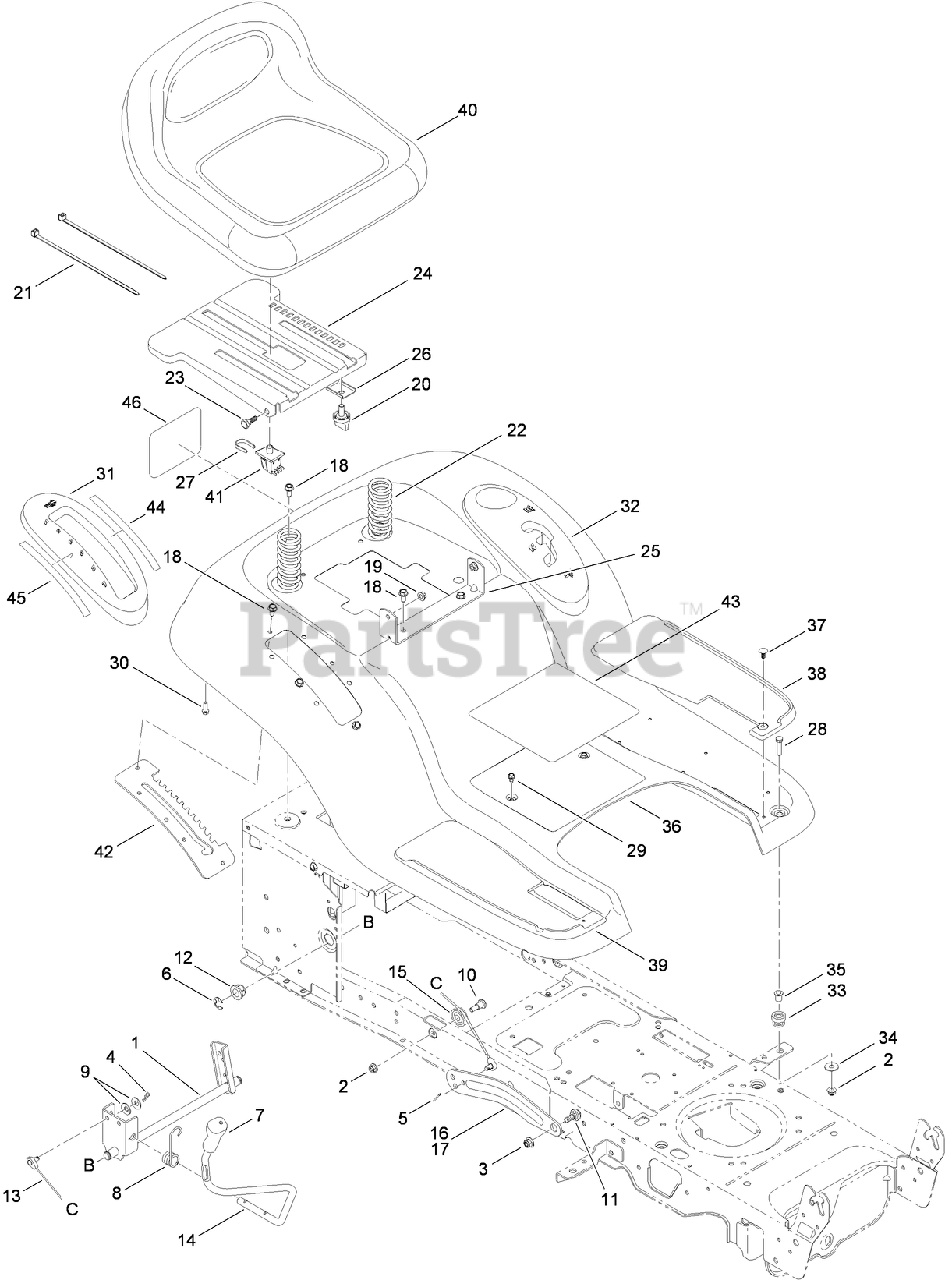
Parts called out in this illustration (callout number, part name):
1	LIFT SHAFT ASM
2	NUT-LOCK, FLANGE
3	NUT-LOCK, FLANGE
4	PIN-COTTER
5	PIN-COTTER
6	RING-E
7	GRIP-HANDLE
8	SPRING-TORSION
9	WASHER-SPRING
10	BOLT-SHOULDER
11	BOLT-SHOULDER
12	BEARING-FLANGE
13	CABLE-LIFT
14	HANDLE-LIFT
15	PULLEY-CABLE
16	ARM-LIFT, RH
17	ARM-LIFT, LH
18	SCREW-TAP
19	NUT-LOCK, FLANGE
21	TIE-CABLE
22	SPRING-COMPRESSION
23	BOLT-SHOULDER
24	BRACKET-MOUNT, SEAT
25	BRACKET-PIVOT, SEAT
26	BRACKET-KNOB, ADJUSTMENT
27	CLIP-RETENSION
28	SCREW-HH
29	SCREW-HWHTF
30	SCREW-TAP
31	COVER-LIFT, LEVER
32	COVER-HOLDER (W/CUP)
33	GROMMET
34	WASHER-FLAT
35	SPACER
36	FENDER
37	CLIP-RATCHET
38	PAD-FOOT, LH
39	PAD-FOOT, RH
41	SWITCH-SEAT
42	BRACKET-LIFT
43	DECAL-SAFETY
44	DECAL-HOC
45	DECAL-PTO
46	DECAL-TORO
